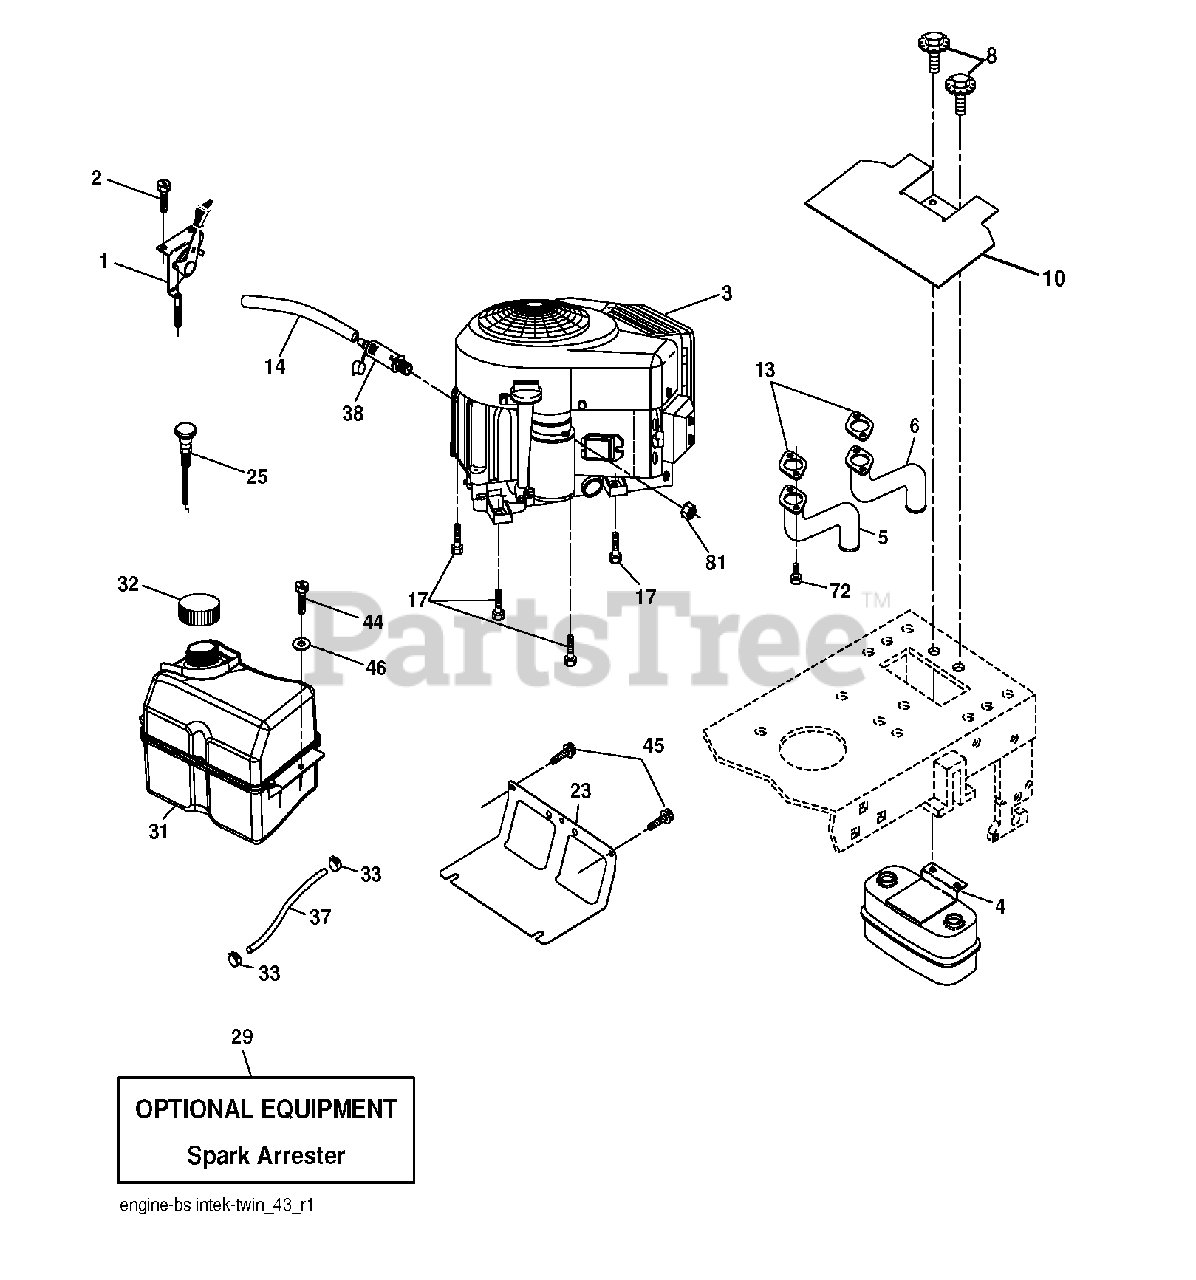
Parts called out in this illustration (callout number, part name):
1	THROTTLE CABLE
2	SCREW.#10 X 0.750.BOS THREAD
4	MUFFLER.TWIN.CYL.LOW.TONE
5	EXHAUST TUBE RH
6	TUBE MANIFOLD LH
8	BOLT, 5/16-18 X 1 3/4
10	RP SHIELD HEAT MUFFLER
13	GASKET.MUFFLER
14	TUBE, DRAIN OIL ASM.
17	SCREW.3/8-16
23	SHEILD.BROWNING.DBR.GUARD
25	CONTROL CHOKE
29	ARRESTER SPARK (OPTIONAL)
32	FUEL CAP
33	HOSE CLAMP
37	LINE.FUEL.20
38	PLUG DRAIN OIL EASY
44	SCREW HEXWSHR 1/4-20X3/4
45	SCREW, 3/8-16X3/4
72	SCREW.SOCKET.HEAD.5/16-18
81	NUT
